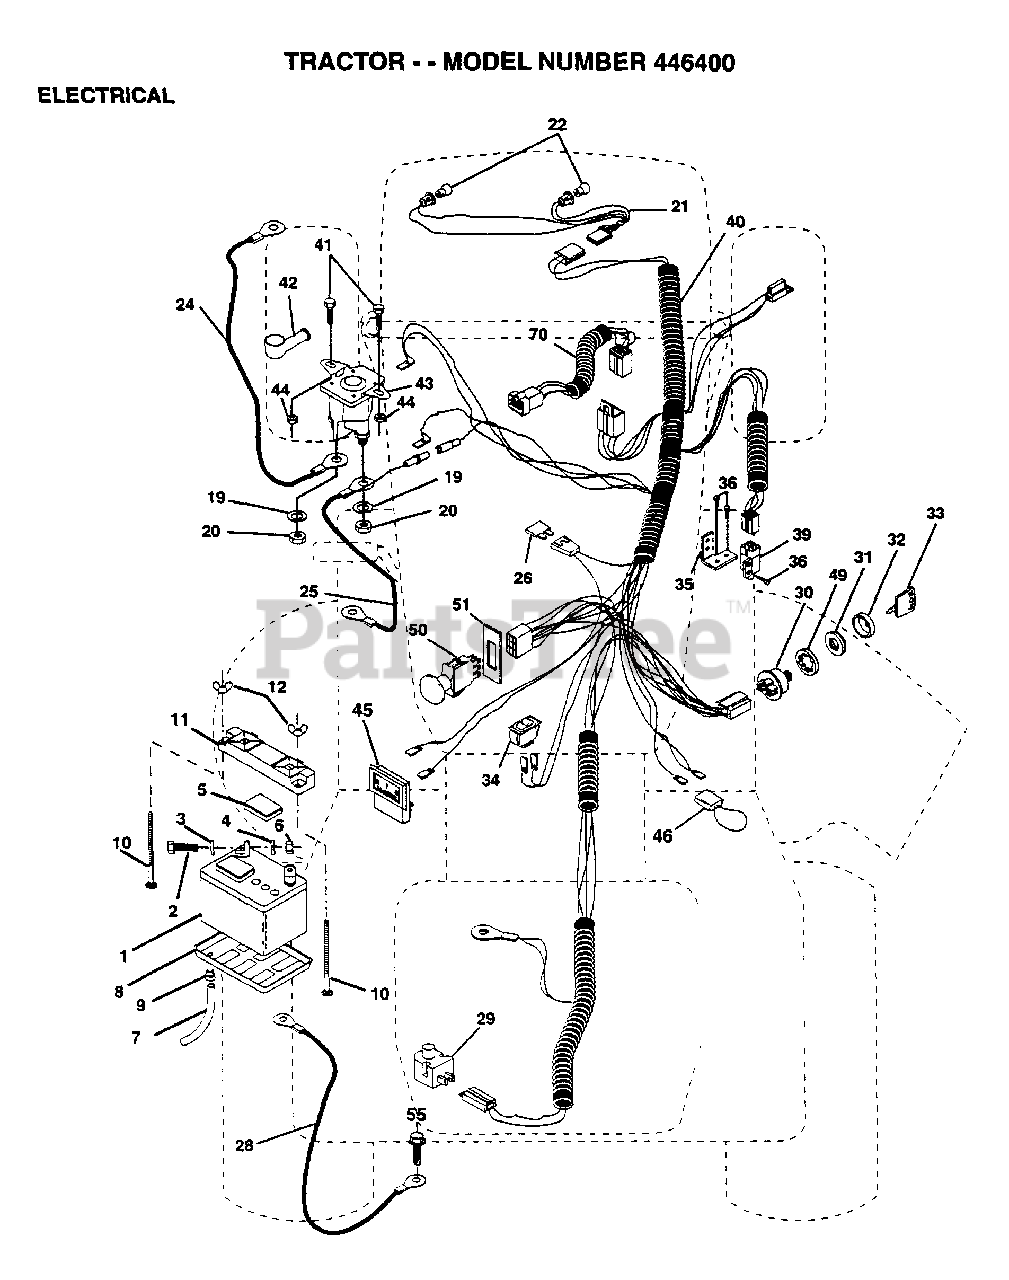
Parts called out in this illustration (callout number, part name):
2	BOLT LT
3	WASHER
4	LOCKWASHER
5	"CAP,BATTERY "
7	"DRAIN TU T, BATT"
8	"TRAY T, BATTERY"
9	HOSE CLAMP T
20	NUT
21	"HARNESS,LIGHT SOC"
22	HEADLAMP BULB
24	CABLE.6GA.22W/16W
25	"CABLE T, BATTERY"
26	FUSE HYT
28	CABLE.GRND.6GA.21
29	SWITCH SEAT
32	COVER KEY SWITCH
33	KEY MLD GEN DELTA
34	SWITCH LT
35	BRACKET LT
36	SCREW
39	SWITCH INTERLOCKT
40	HARNESS.ING.ELEC.
41	BOLT.HX.1/4-20
44	NUT
45	AMMETER
46	PROTECTION LOOP
49	LOCKWASHER
51	RING RETAIN PTO
55	SCREW LT
70	HARNESS.ENG.CV-18
